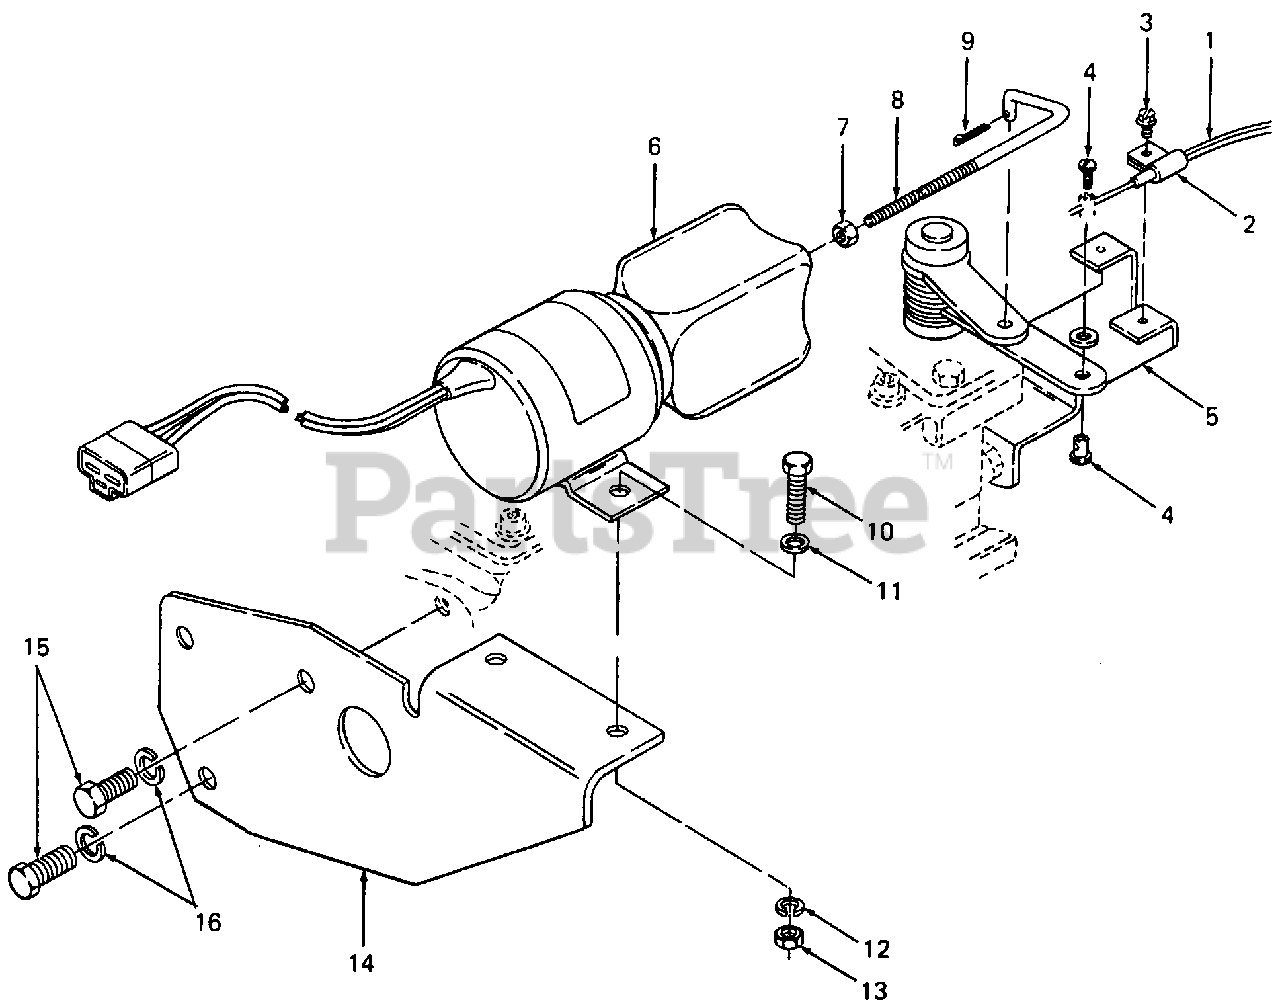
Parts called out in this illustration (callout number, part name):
1	Control, Throttle
2	Clamp, Conduit
3	Screw, Hex "B" Tapp, #10 X .62 Lg
4	Clamp, Swivel Wire
5	Bracket, Control
6	Kit, Solenoid Shutdown
8	Rod, Threaded
9	Pin, Cotter
10	Bolt, Hex, M6 X 20 mm Lg
11	Washer, Flat, .26 X .47 X .065 Thk
13	Nut, Hex, 6 mm
14	Bracket, Solenoid Mtg
15	Bolt, Hex, M8 X 20 mm Lg
